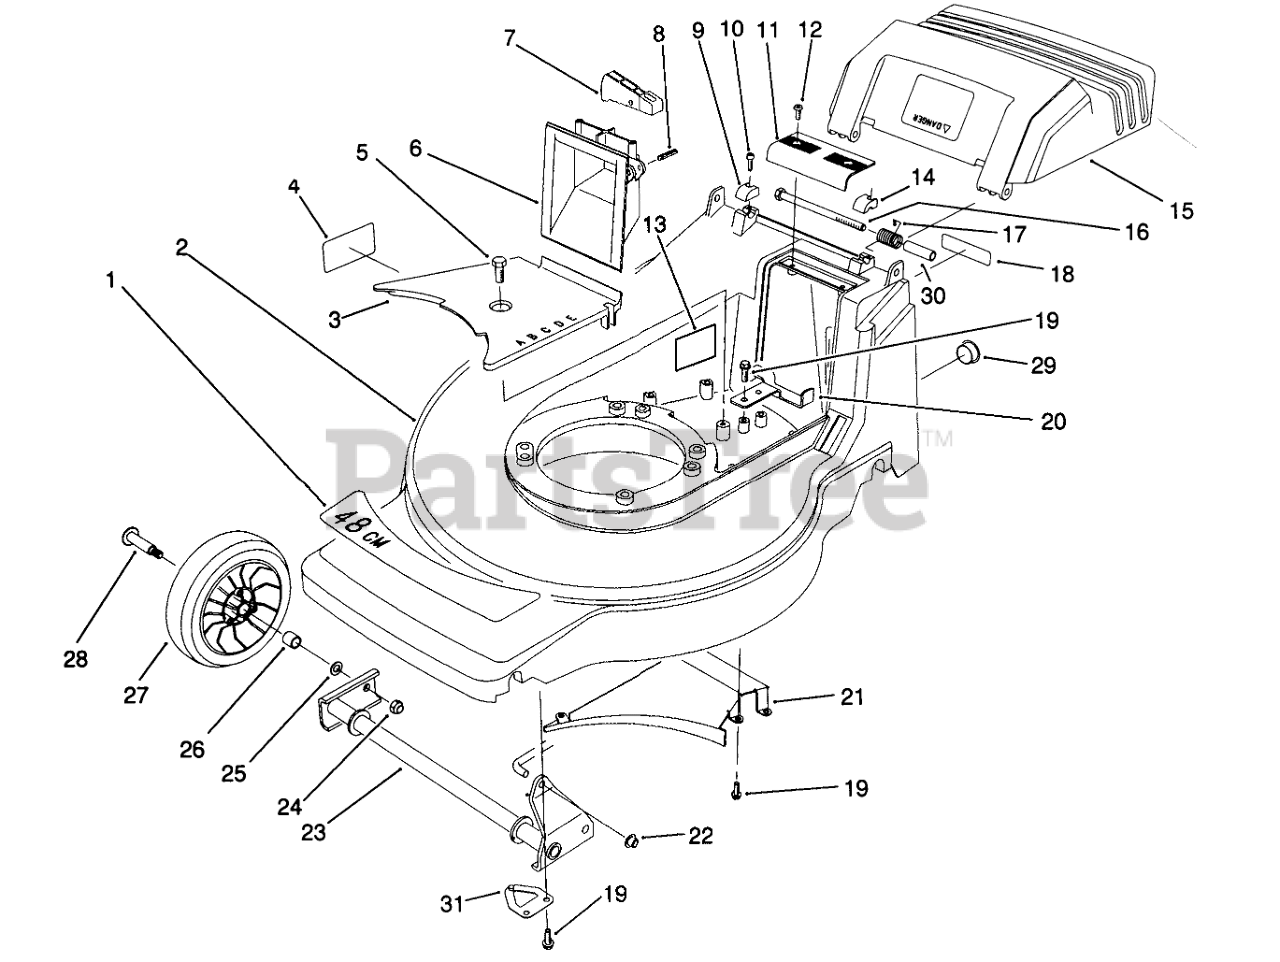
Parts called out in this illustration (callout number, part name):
1	DECAL - DECK
2	Housing-48cm
3	BELT COVER
4	Decal Danger
5	SCREW-HWHTF
6	GRIP - LOWER
7	TRIGGER - HOC
8	PIN-SPIRAL
9	CAP-HINGE BOLT, RH
10	SCREW-HSH
11	GRIP-UPPER
12	SCREW-PPH, PLASTITE
13	Decal-Noise
14	CAP-HINGE BOLT, LH
15	Door-Discharge
16	SCREW-HH
17	DOOR SPRING
18	DECAL FRENCH REGUL.
19	SCREW-HWH
20	REAR BELT GUIDE
21	Ramp-Discharge
22	NUT-PUSH
23	FRONT PIVOT WA
24	Nut
25	WASHER
26	BUSHING
27	Wheel & Tire Assembly (Incl. Ref. #26)
28	BOLT-WHEEL
29	DOME PLUG (DP-1000)
30	SPACER-DOOR
31	SHAFT RETAINER ASM
